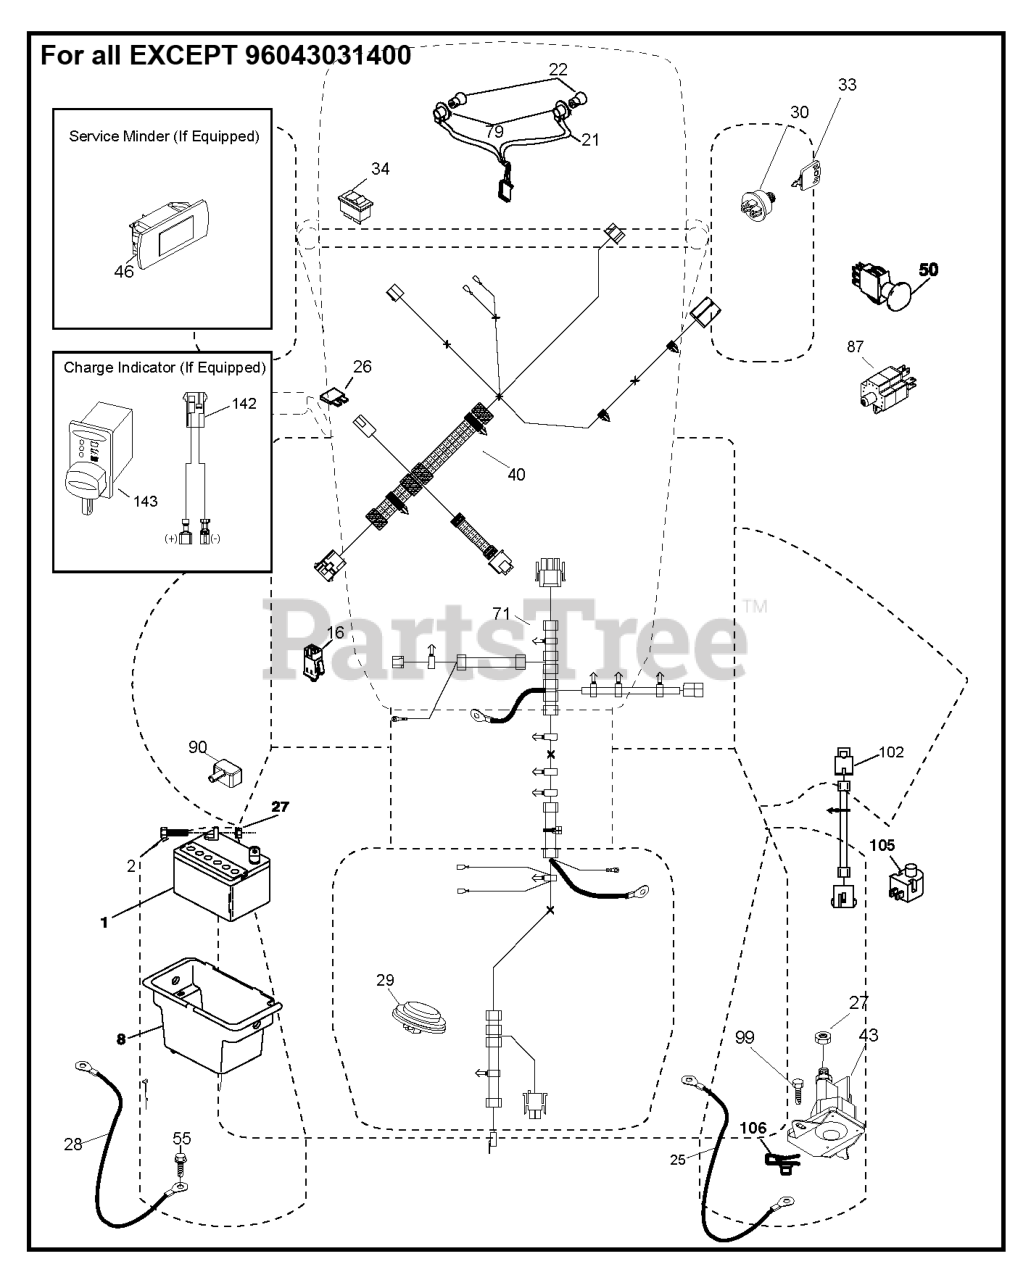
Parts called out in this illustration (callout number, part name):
1	Battery 12 Volt 25 Amp
2	BOLT.HEX.1/4.X.3/4.DICHROMATE
8	BOX.BATTERY.MNT.REAR.L
16	SWITCH INTERLOOK PUSH-IN
21	HARNESS.LIGHT W/4152J BULBS
25	CABLE.BATT.RED.8GA.17
26	FUSE 20AMP
27	Hardware
27	NUT HEX_LRG FLG_1_4-20_LOCK
28	CABLE.GROUND.REAR.BATTERY.8G
29	SWITCH.SEAT.DELTA.OPC.
30	SWITCH.IGN.DELTA.W.LGH.ROS
33	KEY.CHAIN.BLISTER.PACK.GEN.INT
33	KEY.CHAIN.BLISTER.PACK.GEN.USA
40	HARNESS.TEX.DASH.ELEC.REAR BAT
40	HARNESS.TEX.DASH.MAN.REAR BATT
40	HARNESS.DASH.RRBATT.CC.CHG
43	SOLENOID.STARTER.BRASS.PLUNGER
43	Solenoids
46	GUAGE.SRVCMNDR.HRMTR.
50	RP SWITCH.PTO.TERMINAL.STD.RED
55	SCREW 5/16"
71	HARNESS.CHASSIS.RRBATT.RDYSTRT
79	BULB HOLDER ASM.
87	SWITCH.INTRLCK.CLUTCH.
90	COVER.TERMINAL.BATTERY
99	SCREW HEXWSHR 1/4-20X3/4
102	HARNESS.PIGTAIL.VARIATOR.SD
102	HARNESS PIGTAIL PCH TEX ROS
105	REVERSE SWITCH
106	1/4-20 U NUT
142	CHARGE.PORT.PIGTAIL HARNESS
143	CHARGE.PORT
